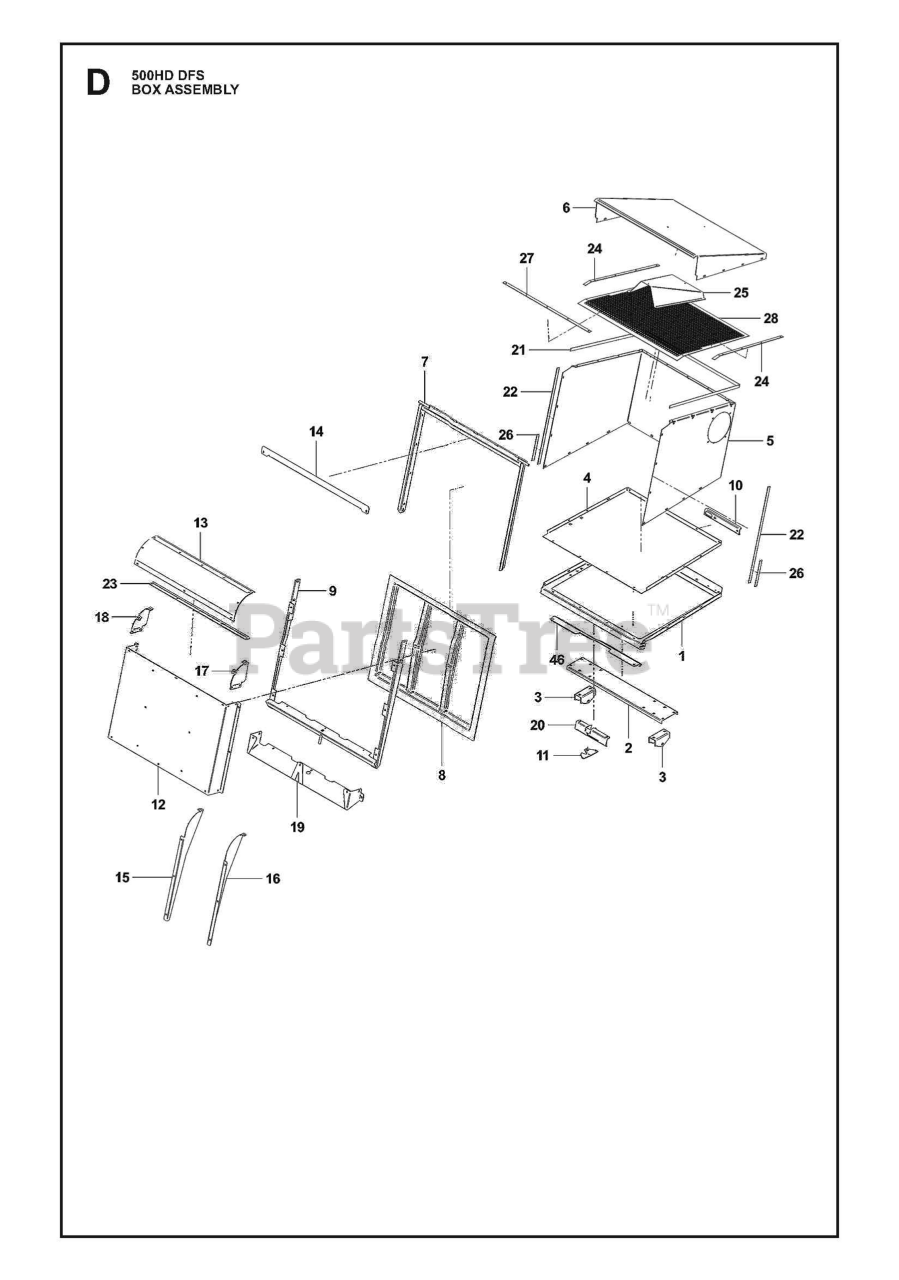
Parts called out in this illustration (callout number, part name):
1	BASES
2	MOUNTS
3	BRACKETS
4	BOX
5	HOUSINGS
6	BOX
7	BOXES
8	DOORS
9	STIFFENERS
10	BRACKETS
11	LATCH
12	GUARDS
13	FLAPS
14	DOORS
15	BRACKETS
16	BRACKETS
17	FLAPS
18	FLAPS
19	BRACKETS
20	PLATES
21	SEALS
22	SEALS
23	FLAPS
24	CLAMPS
25	SUPPORTS
26	SEALS
27	CLAMPS
28	SCREENS
46	BOX
